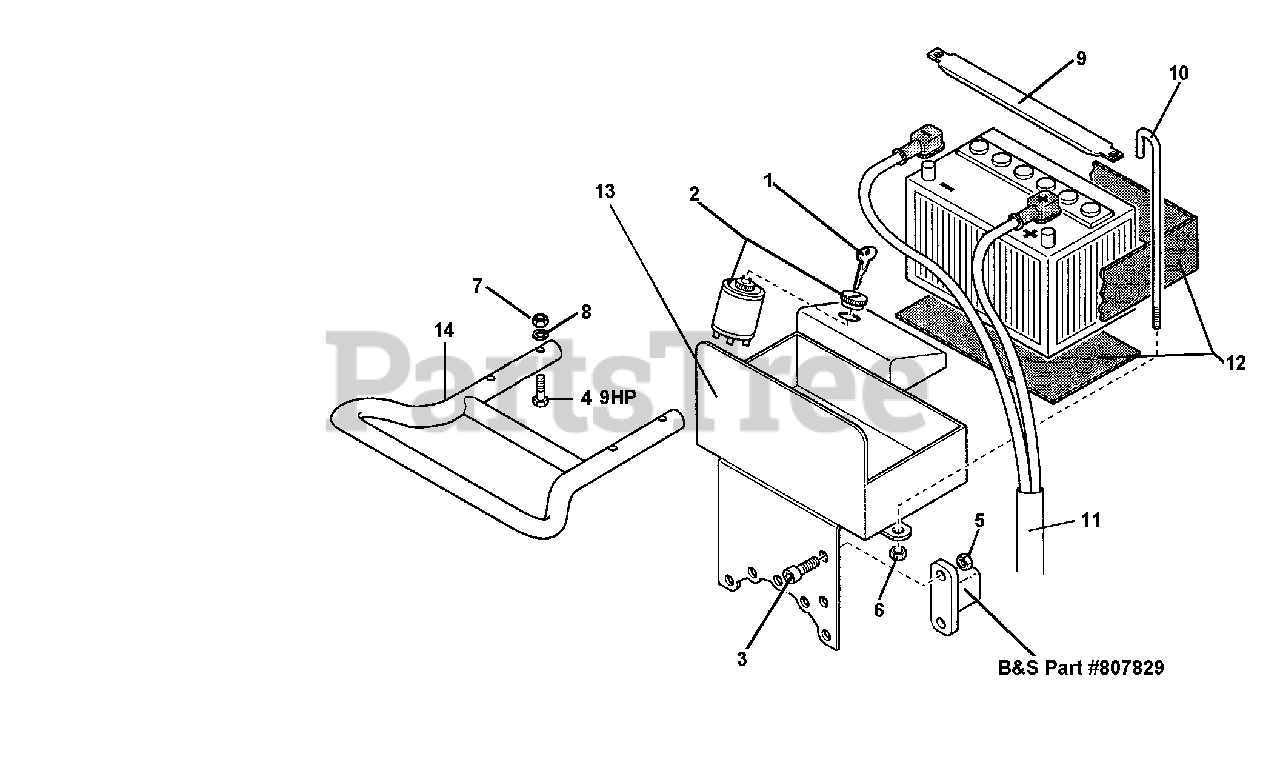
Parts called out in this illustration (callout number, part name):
3	SCREW TE M6X10
4	SCREW M8X60
6	NUT, SELF LOCKING M6
7	NUT, SELF LOCKING M8
8	FLAT WASHER 8.4
9	BATTERY BRACKET
10	BATTERY TIEROD
11	ELECTRIC STARTER CABLES, 9HP VAN.
12	BATTERY PADS
13	BATTERY SUPPORT, 9HP VAN.
14	BUMPER, 9HP VANGUARD
